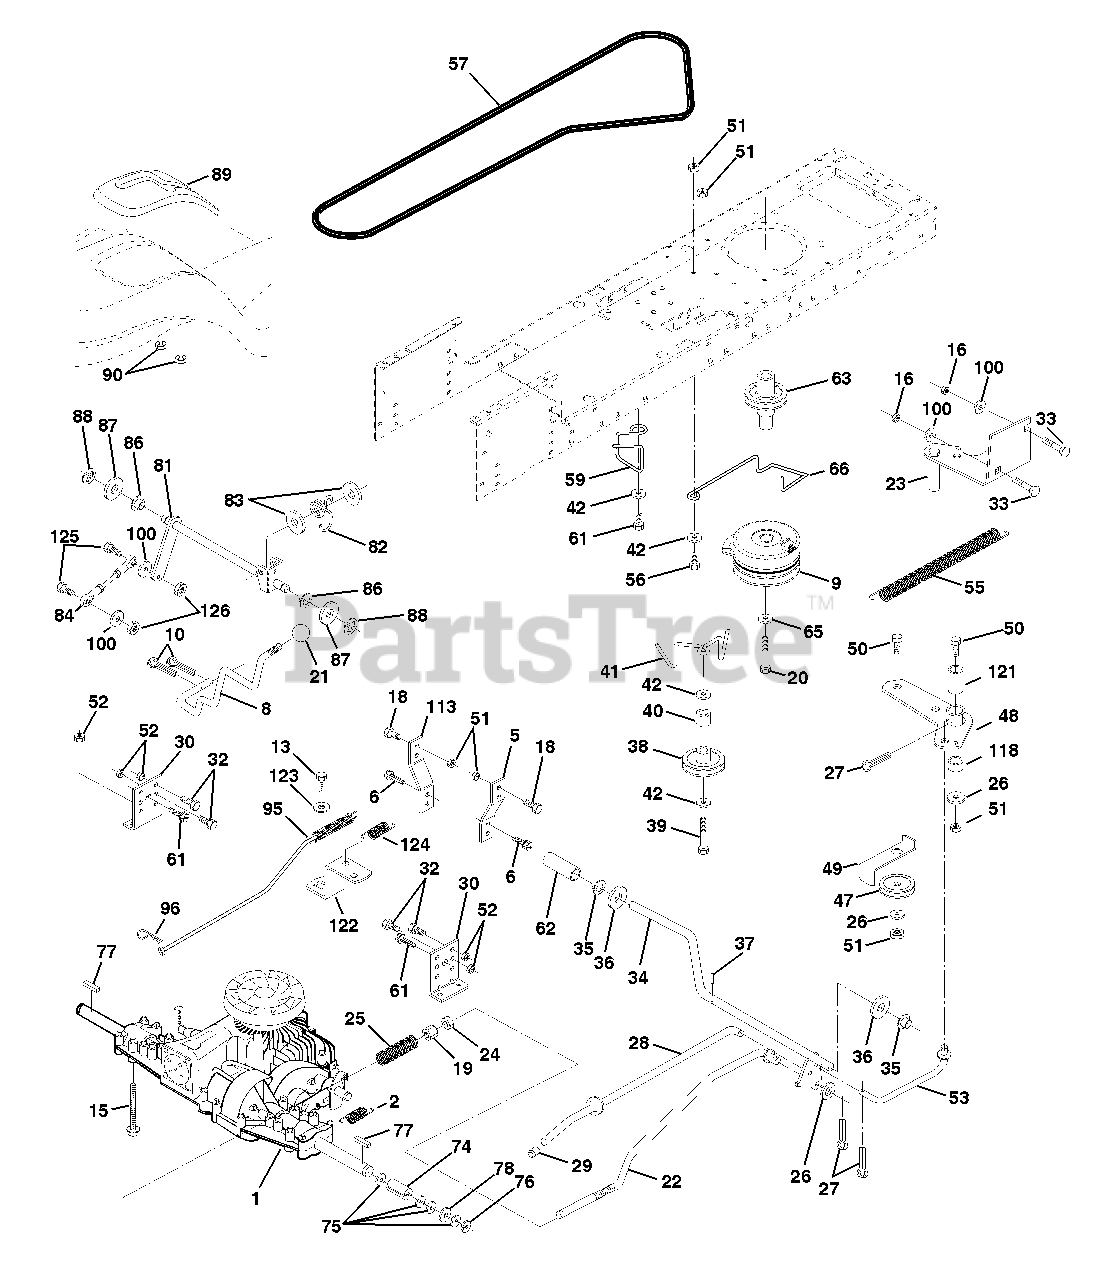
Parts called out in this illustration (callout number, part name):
2	Spring, Return, Brake
5	Strap Torque
6	Screw Thdrol 5/16-18 x 3/4
8	Rod Shift Hydro LT
9	Clutch Electric
10	Pin Cotter 1/8 x 1 CAD
13	Bolt 1/4-28 Unf Gr. 8 W/Patch
15	Bolt Hex 5/16-18 Unc Flghd
16	Nut Lock Hex W/Ins. 5/16-18 Unc P
18	Bolt Fin Hex 3/8-16 Unc x 1 Gr.5
19	Nut Lock Hex W/Ins 3/8-16 Unc
20	Bolt, Hex 7/16-20 x 4-1/4 Ga. 5
21	Knob Deluxe 1/2-13 UNC BLK/BLK
22	Rod, Brake Hydro
23	Bracket Asm Mtg CL
24	Nut Hex Jam 3/8-16 UNC
25	Spring, Brake Rod
26	Washer
27	Pin Cotter 1/8 x 3/4 CAD.
28	Rod, Parking Brake
29	Cap,Parking Brake
30	Bracket, Transaxle
32	Bolt Hex Hd 5/16-18 Unc x 3/4
33	Bolt Carriage 5/16-18 UNC x 3/4
34	Shaft, Foot Pedal
35	Bearing, Nylon
37	Pin, Roll
38	Pulley, Idler, Flat
40	Spacer Split
41	Keeper, Belt Idler
42	Washer 13/32 x 13/16 x 12 Ga
47	Pulley, Idler, V-Groove Plastic
48	Bellcrank Assembly
49	Retainer, Belt Style Spring
50	Bolt
52	Nut Crown Lock 5/16-18
53	Link, Clutch
55	Spring, Return, Clutch
56	Bolt, Fin Hex 3/8-16 UNC x 1 1/4
57	V-Belt, Ground Drive
59	Keeper, Center Span
61	Screw Thdrol. 3/8-16 x 3/4 Ty. TT
62	Cover, Pedal Premium
63	Pulley, Clutch
65	Washer Lock Hvy HLCL Spr 7/16
66	Keeper Belt Engine
74	Spacer, Split
75	Washer 25/32 x 1-1/4 x 16 Ga.
77	Key, Square
78	Washer 25/32 x 1-5/8 x 16 Ga
81	Shaft Asm. Cross Hydro 20" Tires
82	Spring Torsion T/A
83	Washer 17/32 x 3/4 x 16 Ga.
84	Rod, Tie Hydro 20" Tires SPH Ball 4.75
86	Bushing Rod Strig. 629/632 ID
87	Washer 21/32 x 1-1/4 x 16 Ga.
88	Ring Klip #5304-62
89	Console, Hydro STLT
90	Nut Self-Thd Wsh-Hd 1/4 Zinc
95	Control Asm. Bypass Hydro
96	Retainer Spring 1" Zinc/Cad
100	Washer 11/32 x 3/4 x 16 Ga.
118	Spacer Bellcrank
121	Nyliner Clutching STL
122	Plate Bypass PVST
123	Washer 9/32 x 5/8 x 16 Ga.
124	Spring Return PVST
125	Bolt Fin Hex 5/16-18 UNC x 1
126	Nut Lock 5/16-18 UNC
